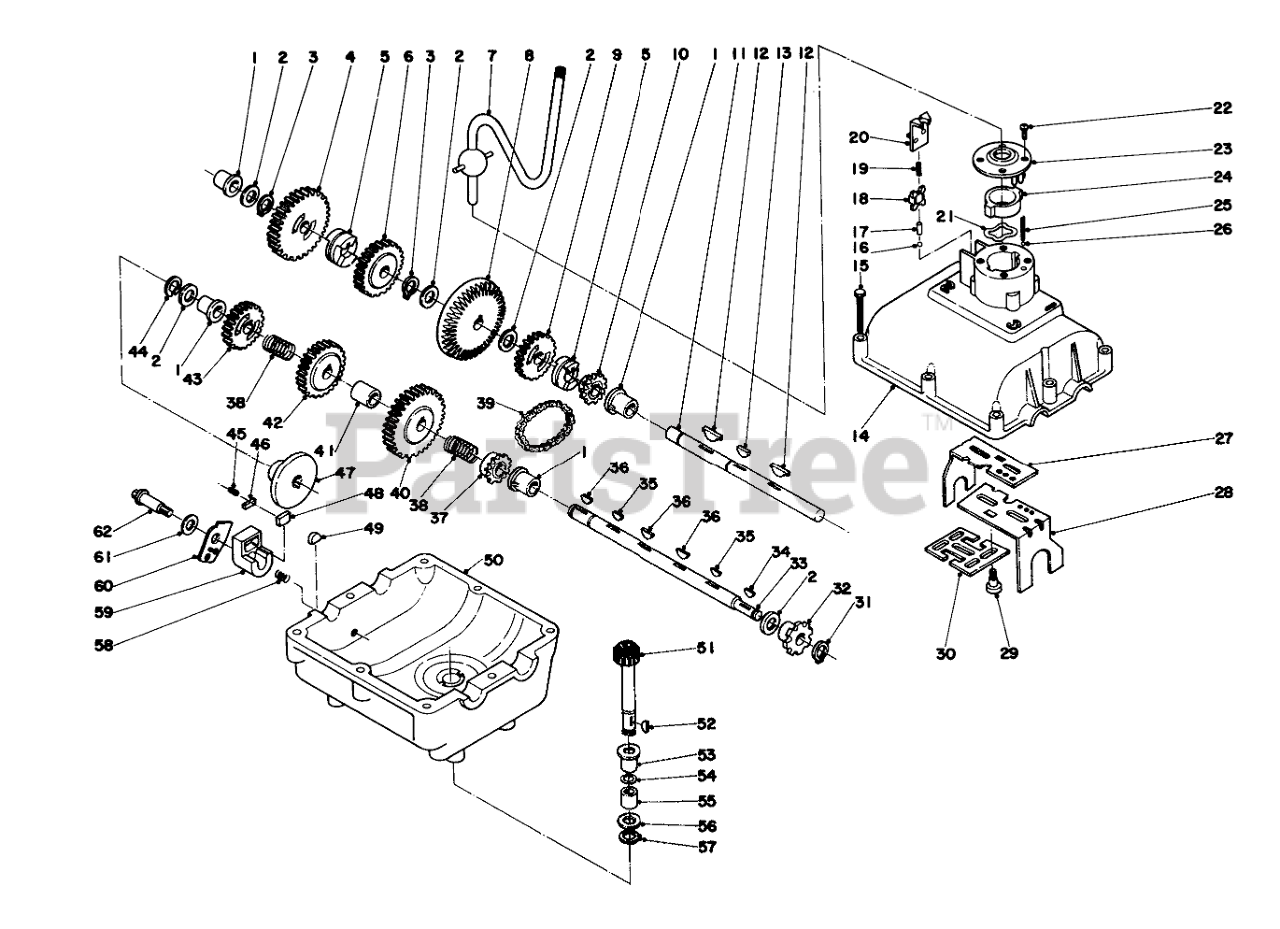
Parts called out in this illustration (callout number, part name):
1	Flange Bearing
2	WASHER KIT
3	Retaining Ring
4	Spur Gear 30T
5	Clutch Collar
6	Spur Gear 25T
7	Shift Lever
8	Bevel Gear 42T
9	Spur Gear 20T
10	Sprocket 12T
11	Drive Shaft
12	Hi Pro Key
13	Woodruff Key
14	Upper Housing
16	Ball Detent
17	Actuating Pin
18	Carrier Contact Assembly
19	Compression Spring
20	Terminal Board
21	Wave Washer
23	Nylon Cover
24	Nylon Insert
25	Detent Spring
26	Detent Ball
27	RH FORK
29	Shoulder Screw
30	Lock-Out Plate
31	Retaining Ring
32	Sprocket 8T
33	Output Shaft
34	Woodruff Key
36	Woodruff Key
37	Sprocket 12T
38	Spring Compression
39	Chain
40	Spur Gear 30T
41	Spacer
42	Spur Gear 25T
43	Spur Gear 20T
44	RETAINING RING
45	Set Screw
46	Spacer
47	BRAKE DISC
48	FRICTION PUCK
49	FRICTION PUCK
50	Lower Housing
51	Input Shaft
52	Woodruff Key
53	Flange Bearing
54	Washer
56	Washer
57	RING-Retaining
58	Compression Spring
59	Brake Jaw
60	Actuating Lever L.H.
61	Washer Kit
62	Shoulder Bolt
